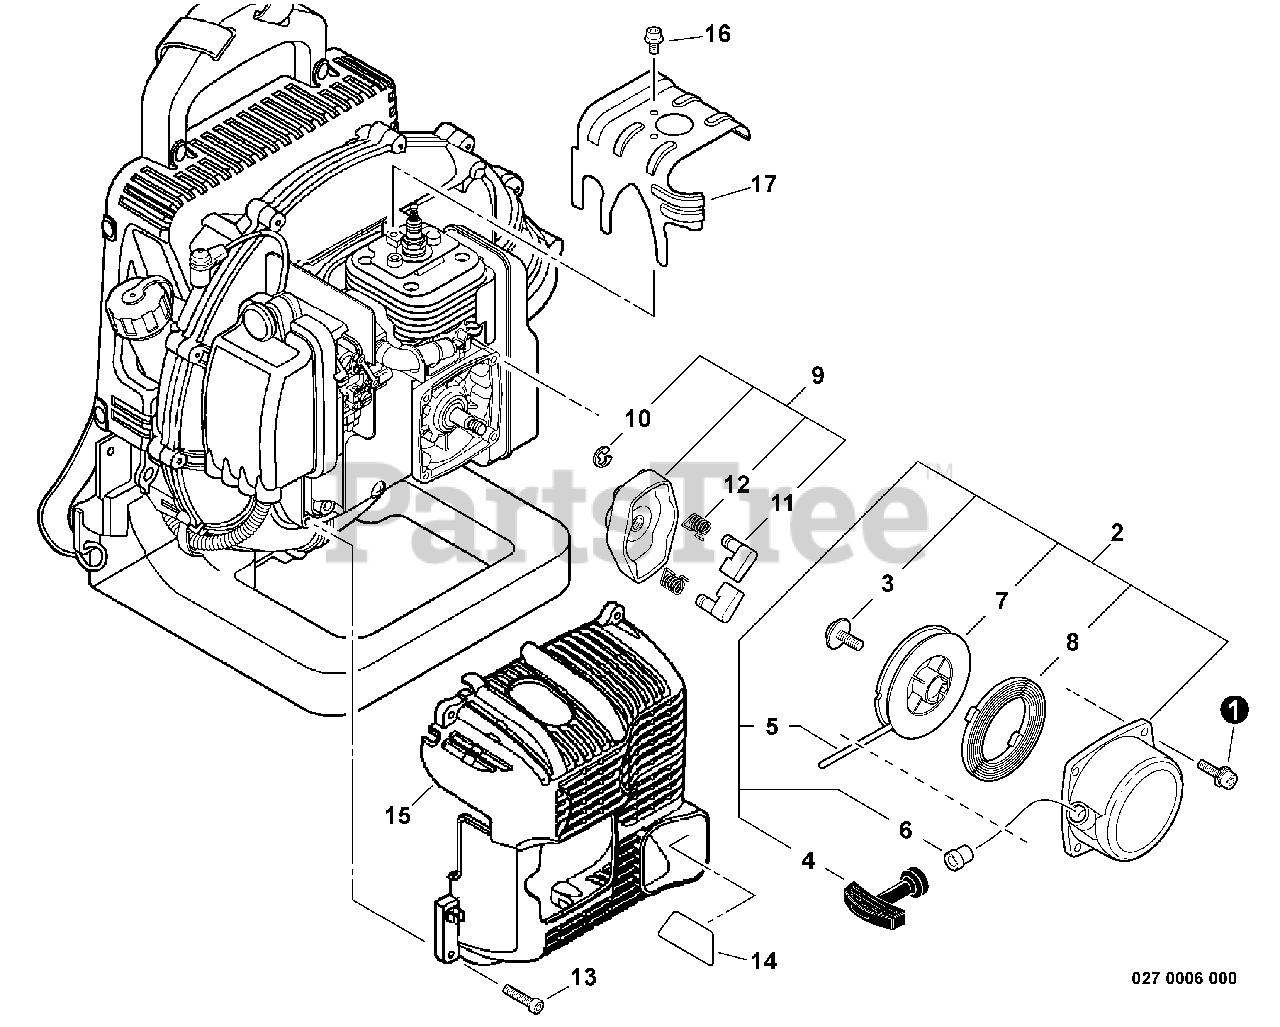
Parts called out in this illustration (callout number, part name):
1	BOLT 5×18
2	STARTER ASSY
3	SCREW
4	GRIP, STARTER
5	ROPE, STARTER
6	GUIDE, ROPE
7	REEL, ROPE
8	SPRING, SPIRAL
9	PAWL ASSY, STARTER
10	E-RING 4
11	PAWL, STARTER
12	SPRING, RETURN
13	SCREW TAPPING 5×20
14	DEFLECTOR, HEAT
15	COVER, ENGINE
16	BOLT 5×8
17	COVER, CYLINDER
